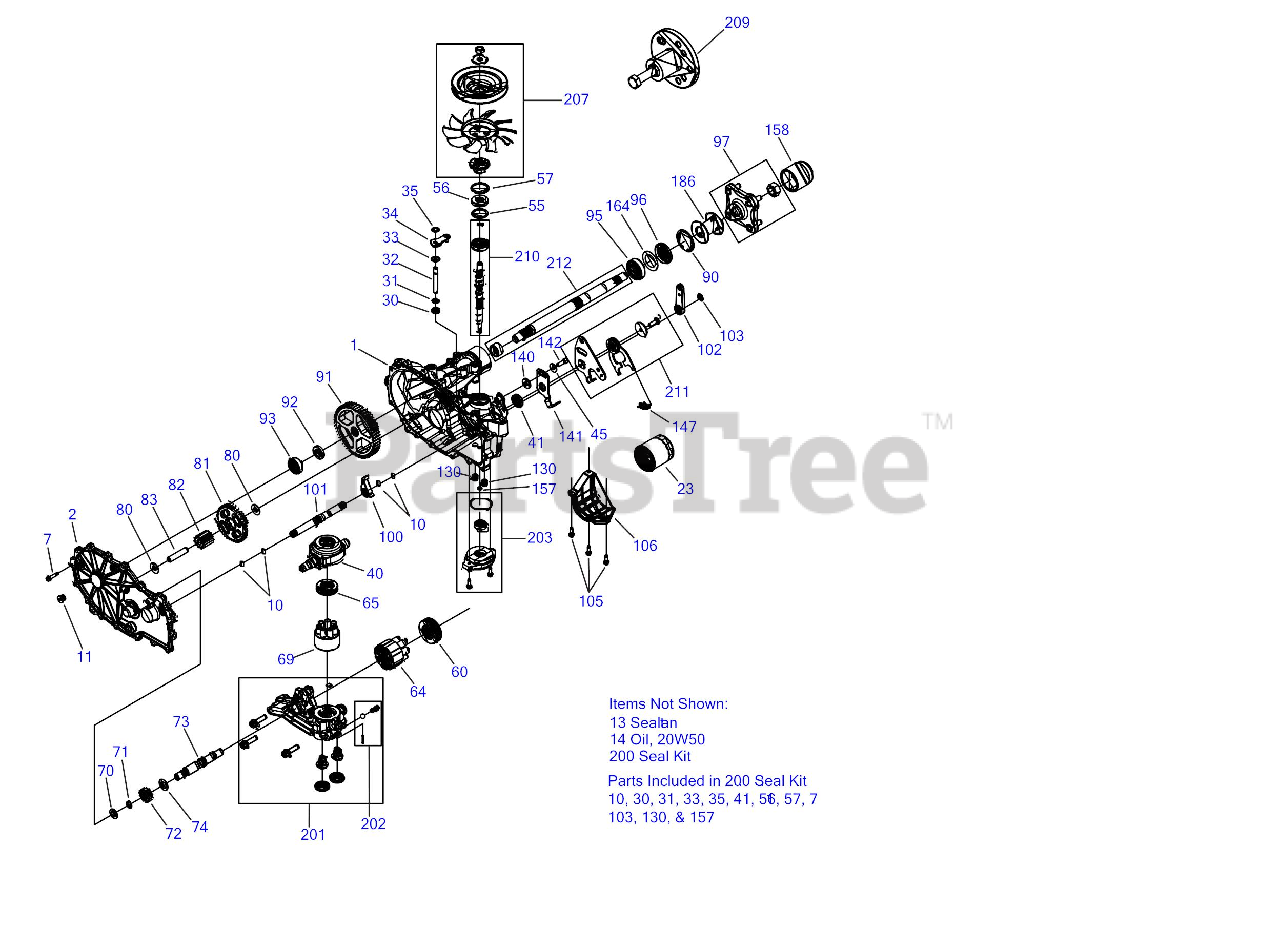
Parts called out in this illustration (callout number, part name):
1	Kit, Main Housing, LH Charge
2	Kit, Side Cover LH
7	Screw, Hex Washer
23	Filter, Spin-On 2.6 x 3.0
30	Seal, Lip, .375 x .75 x .25
31	Ring, Retaining .375 External
32	Rod, Bypass
33	Ring Retaining .750 Internal
34	Arm, Bypass
35	Ring, Ret .375 External
40	Trunnion, Swashplate
41	Seal, Lip 18 x 32 x 7
45	Washer, .34 x .88 x .06
55	Washer, 1.23 x 1.57 x .04
56	Seal, Lip 17 x 40 x 7
57	Ring Retaining Internal
60	Bearing, Thrust 35 x 62 x 18
64	Kit, 16cc Cylinder Block Assembly
65	Thrust Bearing, 30 x 52 x 13
69	Kit, Block, 7 Piston
70	Washer, .63 x 1.00 x .05
71	Ring, Reatining, Motor Shaft
72	Gear, 14T (Steel)
73	Shaft, Motor
74	Washer, .71 x 1.16 x .04
81	Gear, 45T
82	Gear, 11T (Steel)
83	Pin, Jackshaft
90	Ring, Retaining 2.25 Internal
91	Gear, 54T
92	Spacer, .750 x 1.00 x .257
93	Bearing, Ball 3/4 x 40mm x 12mm
95	Bearing, Ball 25.4 x 52 x 15
96	Seal, Lip, 1.0 x 2.06 x .38
97	Kit, Hub 4-Bolt
100	Pawl, Brake
101	Kit, brake Shaft
102	Handle, Actuating
103	Ring, Retaining, External .438
105	Screw, Hex Washer 1/4-20 x .75
106	Guard, Filter, LH
111	Kit, Fitting 1/2 Beaded 9/16 SAE
130	Tube, Charge Triple O-Ring
140	Spacer, .320 x 1.005 x .150
141	Arm, Return Left
142	SHCS, 5/16-24 x 7/8 (W/Patch)
147	Spring, Extension
157	Seal, Gerotor .281 x .420 x .160
158	Cap, Axle
164	Spacer, 1.355 x 2.035 x .021
186	Tube, Axle 2.03
200	Kit. Seal, ZT-2800
201	Kit, Center Section LH Charge
202	Kit, Charge Relief
203	Kit, Charge
207	Kit, Fan Pulley
207	Fan Only
207	Pulley Hub
209	Kit, Hub Puller
210	Kit, Input Shaft
211	Kit, RTN Bidirectional
212	Kit, Shaft Axle
